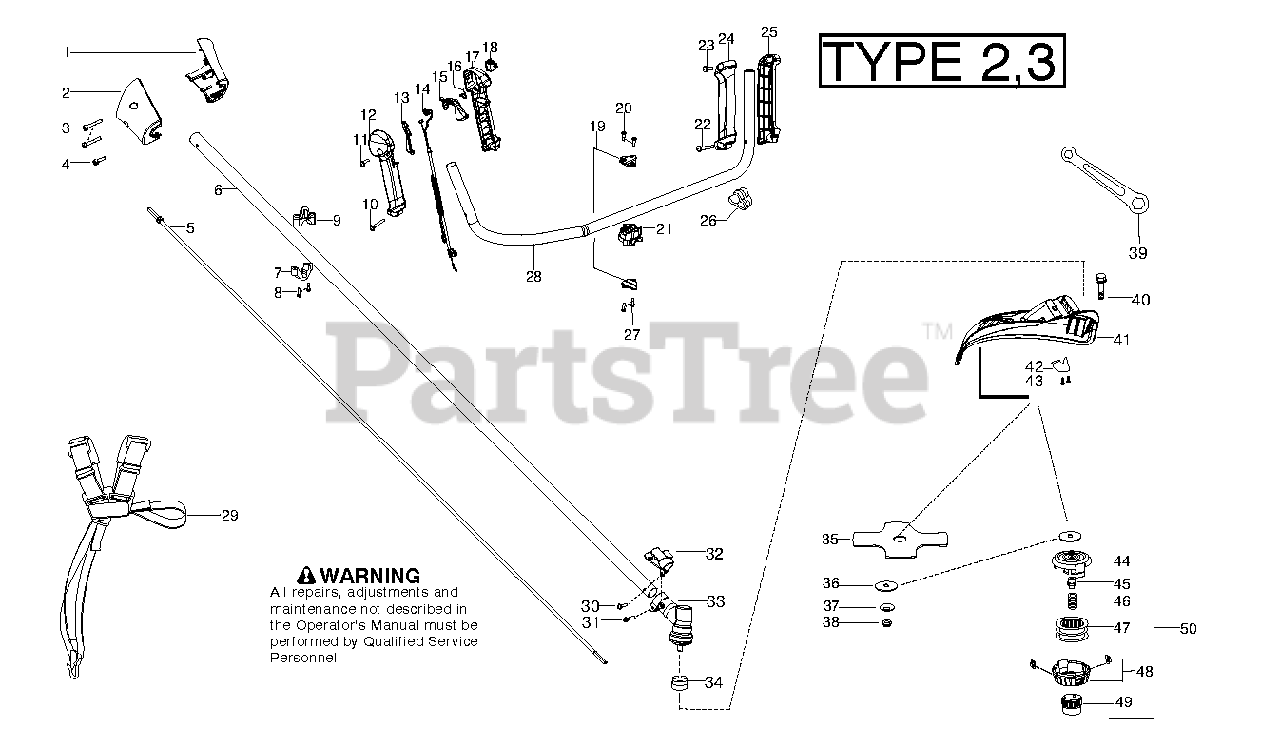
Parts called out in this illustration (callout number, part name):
1	NOSECONE LH LT33 BUL
2	NOSECONE RH LT33 BUL
3	SCREW M4 X 1.75 PT 16MM
4	SCREW-10-16 X 1/2, TYPE 2
5	FLEXSHAFT 57"
6	Drive Shaft Assembly
7	CLAMP HARNESS LOWER
9	CLAMP HARNESS UPPER
10	SCREW #10 PLASTITE 1.362
12	HANDLE HOUSING
13	THROTTLE LOCKOUT
19	CLAMP BRACKET
20	SCREW-10-14 X 13/16 (PL
22	SCREW #10 PLASTITE 1.362
27	SCREW-10-14 X 13/16 (PL
28	ASSY HANDLEBAR BULLH
29	HARNESS BLACK NO LABEL
30	SCREW 8-16 X 9/16 (PLAS
31	SCREW - CARB. ADAPTOR
34	DUST CUP , BLADE
35	ASSEMBLY
36	WASHER,BLADE RETAINING
37	Belleville Washer
38	NUT-FLANGE (LH)
40	SCREW 1/4-20 X 7/8 (TAP
41	KIT
46	SPRING
47	SPOOL WOUND LH 15 FT.
49	KNOB
50	Trimmer Head, P25
